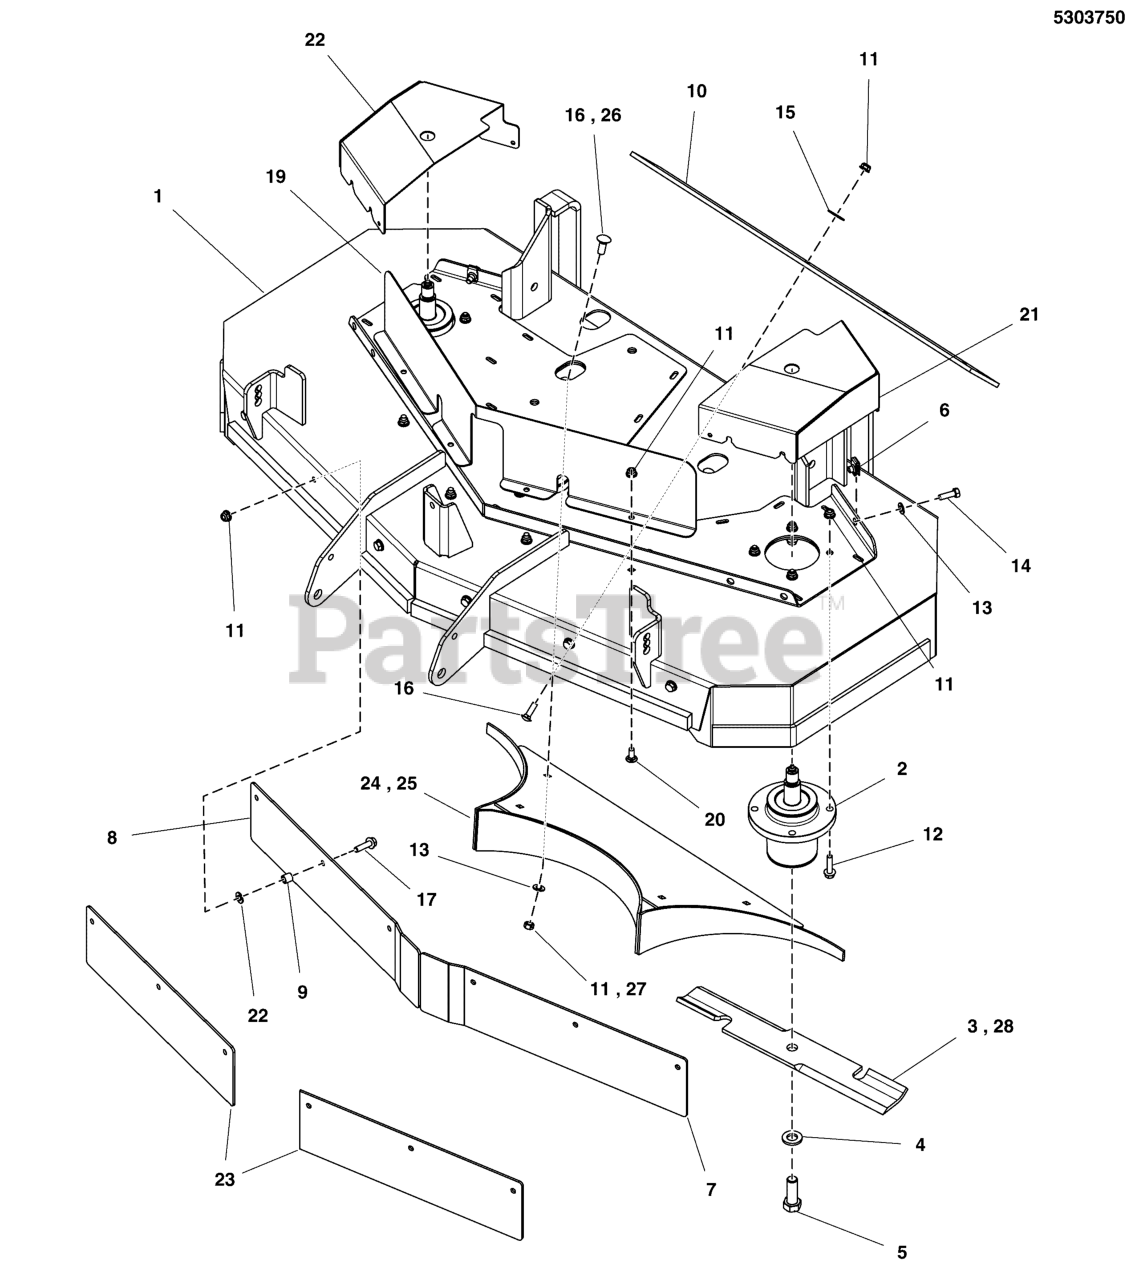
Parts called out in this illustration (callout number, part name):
1	DECK SHELL W/ DECALS, 48RDCE, FW35
2	SPINDLE, ASSM, ALUMINUM - 5.25
3	BLADES, SET OF THREE (3); 16.25 X.25 X 2.5, 1 X 3.5
4	WASHER, BLADE BOLT, 9/16" F436, CZ
5	BOLT, 5/8-11 X 1-3/4 GD8
6	BODY CLIP, 5/16-18-7GA MATERIAL
7	BAFFLE, FRONT DISCHARGE, 48 RH CCW - RED
8	BAFFLE, FRONT DISCHARGE, 48 LH CCW - RED
9	SPACER, .33 X .50 X .50, YZ
10	FLAP, CCW RD
11	NUT, 5/16-18 HEX NYLOCK FLANGE NUT
12	BOLT, Flange Head, 5/16-18 x 1-1/4
13	WASHER, 5/16" SAE
14	BOLT, 5/16-18 X 1-1/4" GD5 YZ
15	WASHER, 5/16" Fender
16	BOLT, 5/16-18 X 1, CARRIAGE, GD5, CZ
17	BOLT, 5/16-18 X 3/4 GD5
19	GUARD, FRONT DECK, FW35 48 RD - RED
20	BOLT, 5/16-18 X 3/4, CARRIAGE, GD5, CZ
21	WELD, GUARD, FW35 48, LH - RED
22	WELD, GUARD, FW35 48, RH - RED
23	BAFFLE, FRONT, FW35-48, REAR DISCHARGE - RED
24	WELD, REAR BAFFLE, FW35 48RD - RED
25	WELD, REAR BAFFLE, 48RD, SHORT - BLK
26	BOLT, 5/16-18 X 3/4, CARRIAGE, GD5, CZ
27	NUT, 5/16-1/8, HEX, CNTR LK, ZINC PHOS/OIL
28	BLADE SET, MULCH, 48 DECK (SET OF 3)
